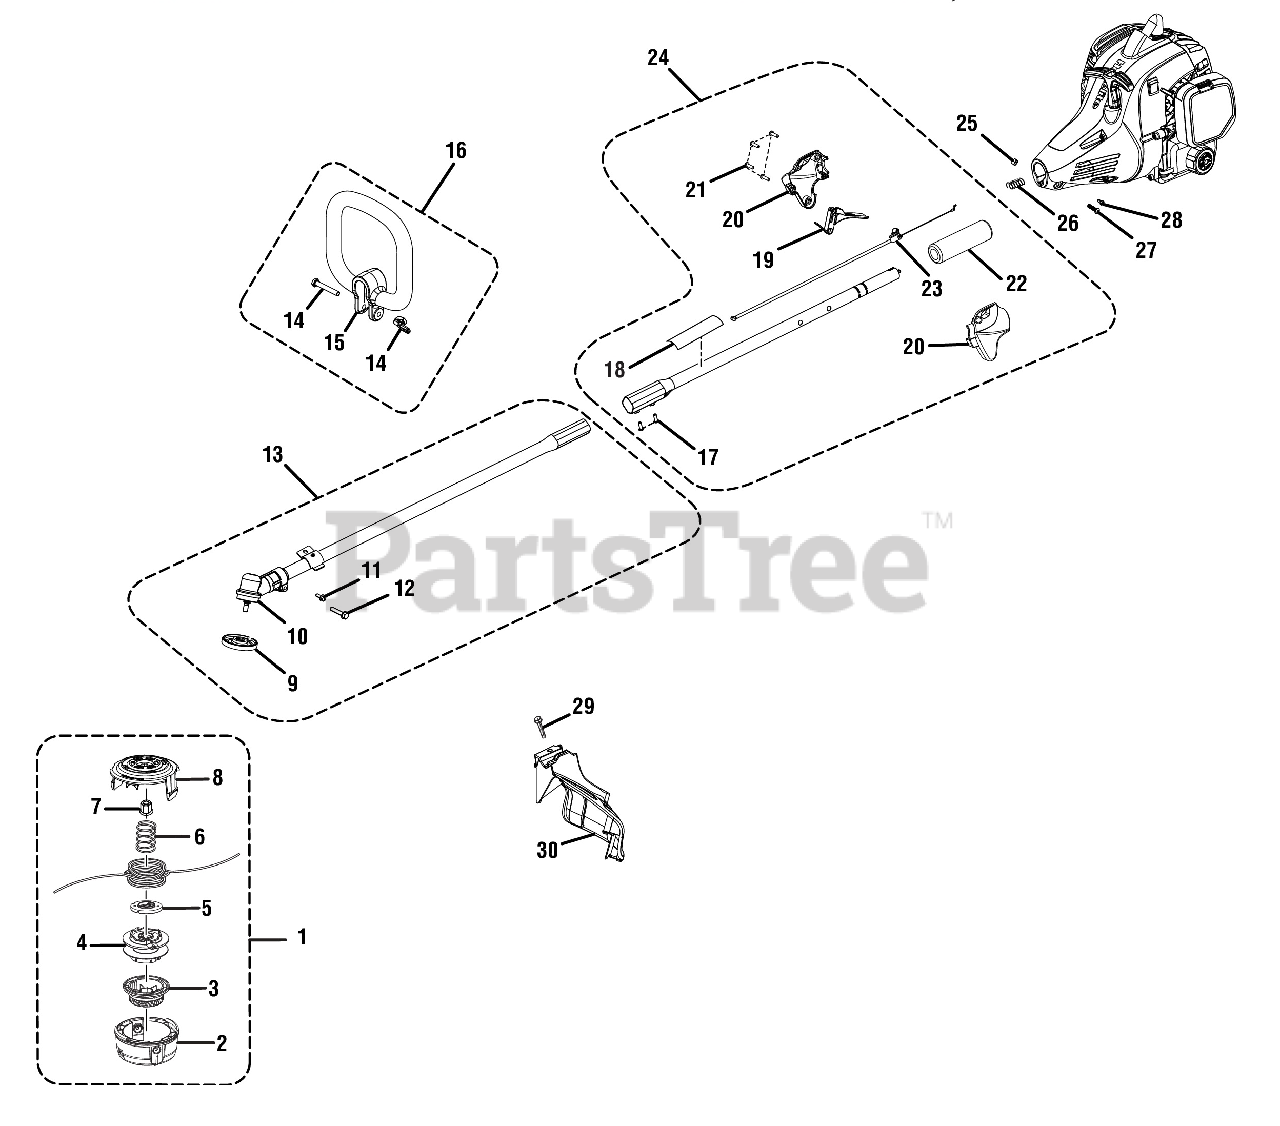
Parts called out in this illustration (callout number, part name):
1	Trimmer Head Assembly
2	Lower Housing
3	Bump Knob (Gray)
4	Spool Assembly
5	String Guide
6	Compression Spring
7	Hex Nut (M8, Left Hand Threads)
8	Upper Housing
9	Flanged Washer
10	Gear Case Assembly
11	Screw w/Washer (10-24 x 5/8 in., Hex Hd. T.F.)
12	Screw (1/4-20 x 1-1/4 in., Hex Washer Hd. S.T.)
13	Lower Boom Assembly
14	Fastener Parts Kit
15	Front Handle
16	Front Handle Assembly
17	Set Screw (M5 x 10 mm, Hex Soc. Hd.)
18	Icon Warning Label
19	Throttle Trigger
20	Trigger Handle Assembly
21	Screw (M4 x 20 mm, T20 Torx Pan Hd. T.Fl.)
22	Rubber Grip
23	Throttle Cable
24	Boom Assembly
25	Hex Nut (M6.3 x 1)
26	Compression Spring
27	Screw (M6 x 20 mm, T27 Torx Button Hd.)
28	Screw (M4 x 8 mm, T25 Torx Pan Hd. T.F.)
29	SCREW (#1/4-20 X 1-1/4 in. HEX WASHER HD.)
30	Grass Deflector Assembly
